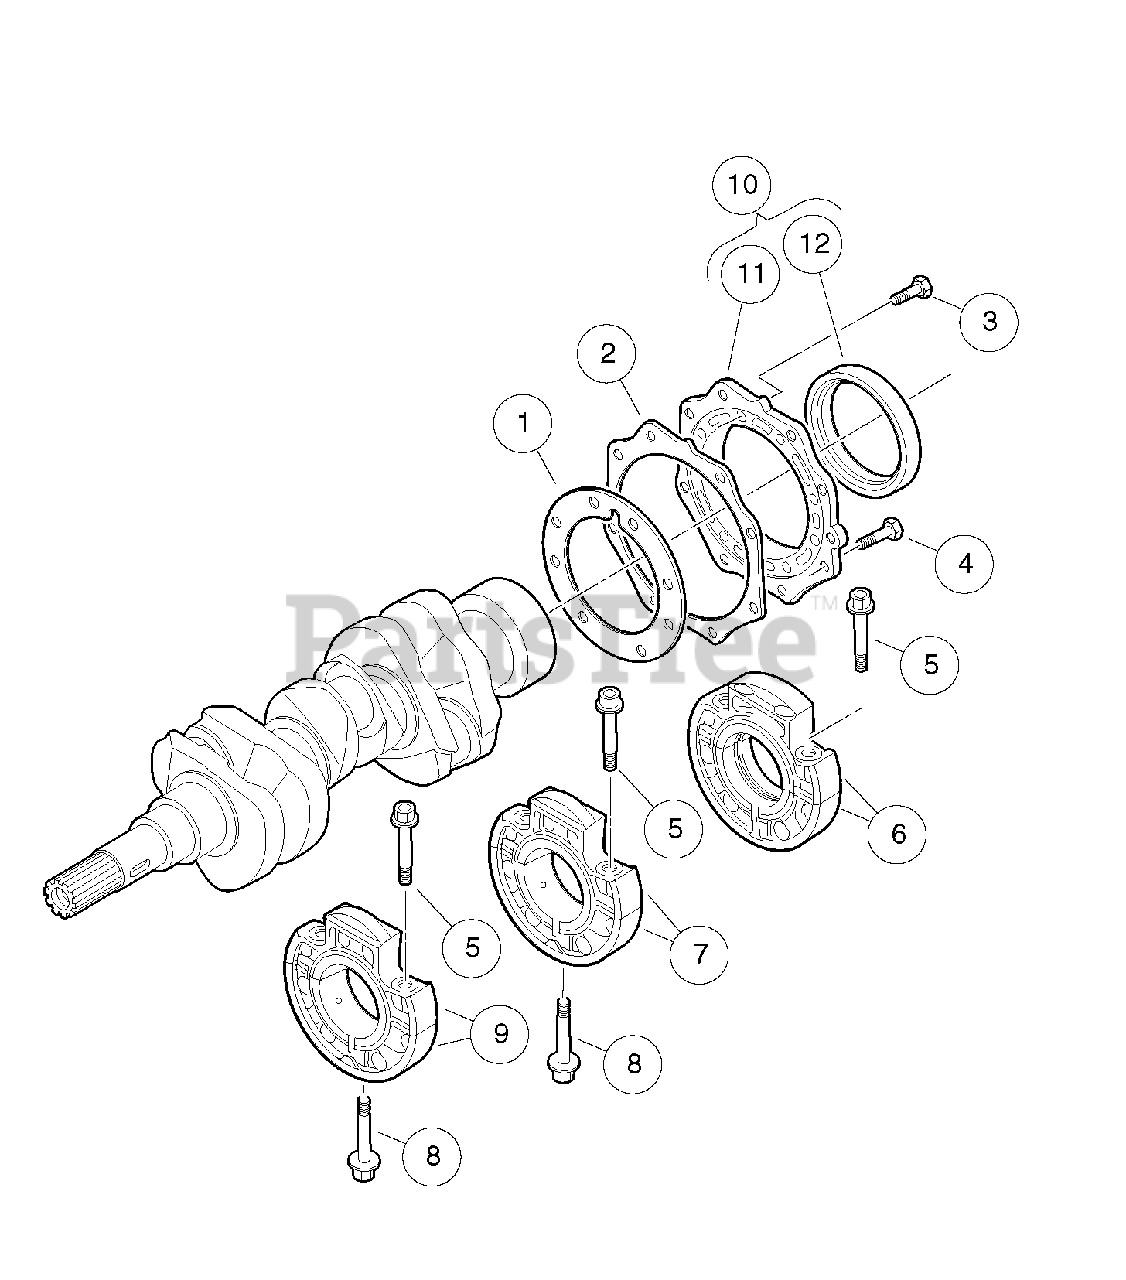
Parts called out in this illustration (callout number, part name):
1	Gasket, Bearing Case
2	Gasket, Cover
3	Bolt, M6 X 1 X 20
4	Bolt, M6 X 1 X 22
5	Bolt, Bearing Case, Top
6	Assy Case, Main Brg, First
7	Assy Case, Main Brg, Sec
8	Bolt, Bearing Case, Bottom
9	Assy Case, Main Brg, Third
10	Assy, Cover, Bearing Case
11	Cover, Bearing Case
